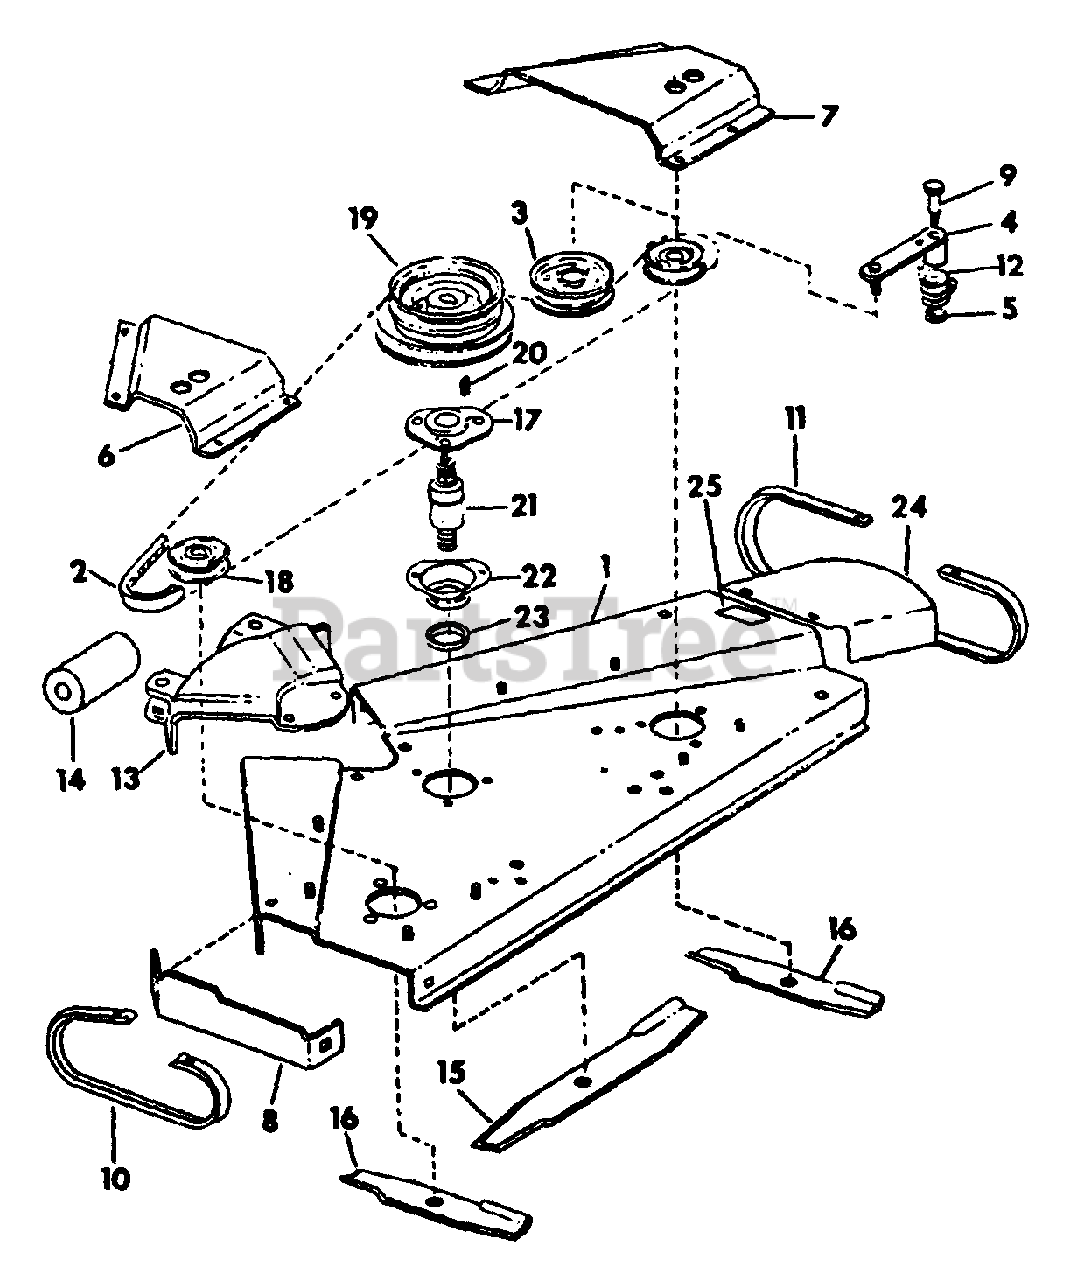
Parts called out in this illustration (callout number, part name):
1	HOUSING ASSY W/PRODUCT GRAPHIC, 57801-C2, ROTOR
2	BELT, SPINDLE DRIVE -38 IN. BLADE-
3	PULLEY, FLAT IDLER
4	ARM ASSY, IDLER
5	NUT, CENTER LOCK
6	SHIELD, BELT LH
7	SHIELD, BELT RH
8	SIDE, HOUSING LH -38 IN. BLADE-
9	BOLT, IDLER ARM PIVOT
10	RUNNER, MOWER LH
11	RUNNER, MOWER RH
12	SPRING, TORSION
13	HOUSING CENTER
14	ROLLER FRONT
15	BLADE, CENTER -38 IN. BLADE- -HARD SURFACED-
15	BLADE, CENTER -38 IN. BLADE-
16	BLADE, OUTER -38 IN. BLADE- -HARD SURFACED-
16	BLADE OR OUTER -38 IN. BLADE-
17	CAP, SPINDLE HOUSING
18	PULLEY, OUTER
19	PULLEY, CENTER
20	KEY, 1/4 x 3/4 WOODRUFF 91
21	BEARING, BALL
22	HOUSING SPINDLE
23	CUP, SPINDLE
24	DEFLECTOR, 38 IN.
25	PRODUCT GRAPHIC, CAUTION
18494-R1	BOLT, 3/8 X 1 ZND HEX-HD MACH
20914-R1	BOLT, 1/2 x 7-1/2 C-Z SQ-NK CRG
21904-R1	WASHER, 15/32 x 7/8 x 11 GA C-Z
22476-R1	BOLT, 3/8 x 1-1/8 ZND SQ-W CRG
24764-R1	NUT, 3/8-16 ZND NYLON LOCK
477243-R1	WASHER, .781 x 2 x 16 GA ZND)
